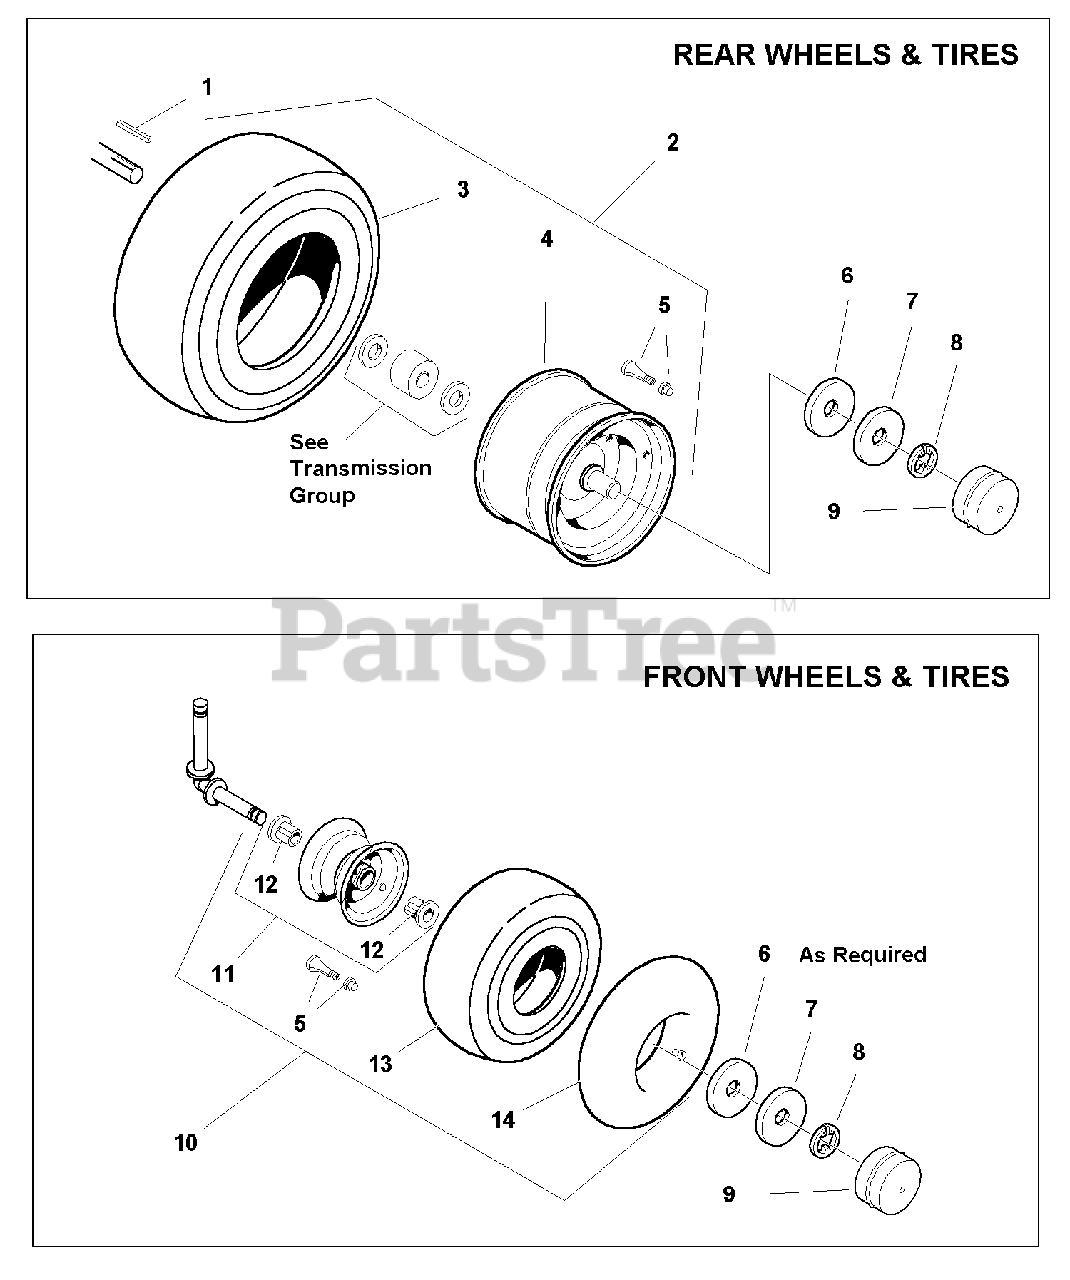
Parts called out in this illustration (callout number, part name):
1	KEY, 3/16 x 2
2	WHEEL & TIRE ASSEMBLY
3	TIRE, 20 x 8 - 8 Super Trac II
4	WHEEL, 7 x 8
5	VALVE STEM & CAP ASSEMBLY
10	WHEEL & TIRE ASSEMBLY (Includes Ref. Nos. 5, 11, 12, 13 & 14)
11	WHEEL & BUSHINGS ASSEMBLY (Includes Ref. No. 12)
12	BEARING
13	TIRE, 15 X 6.5 - 6 Super Trac II
